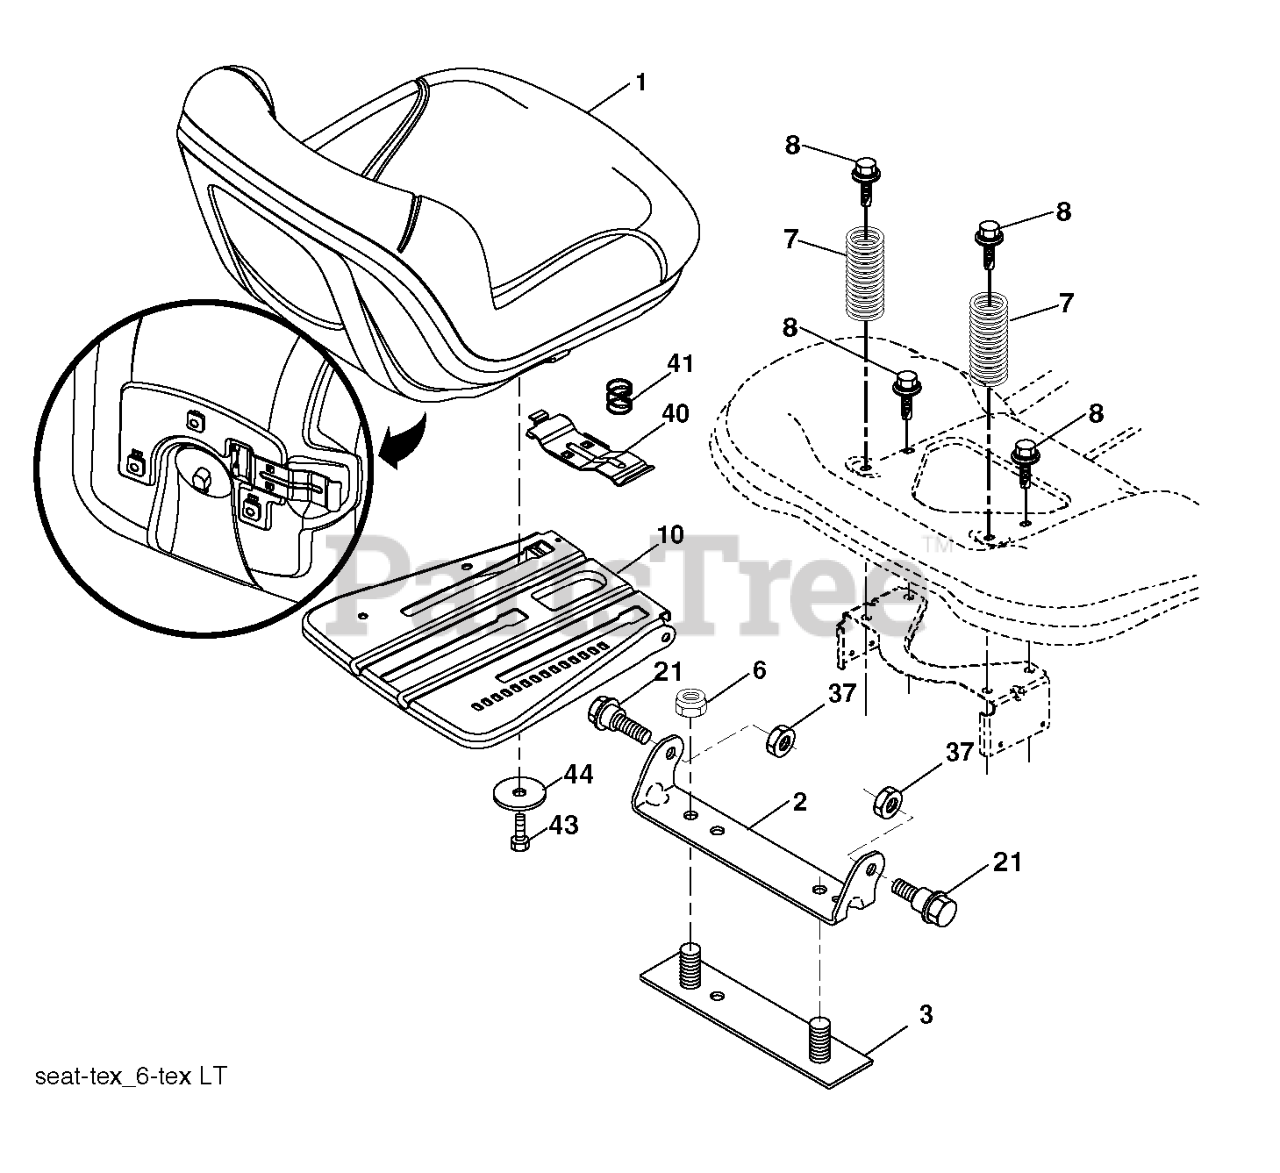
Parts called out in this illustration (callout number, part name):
2	SHAFT.ASM.CROSS.LIFT
7	GRIP.HANDLE.LIFT.PVC.BLACK
10	SPRING.TORSION.LIFT.HANDLE
41	NUT.LIFT LNK.7/16-2
87	PIN.COTTER.7/16.BOW TI.
89	WASHER.CLEAR.ZINC
97	SCREW, 3/8-16X3/4
98	DECK ATTACHMENT FRONT LINK WEL
114	NUT **
